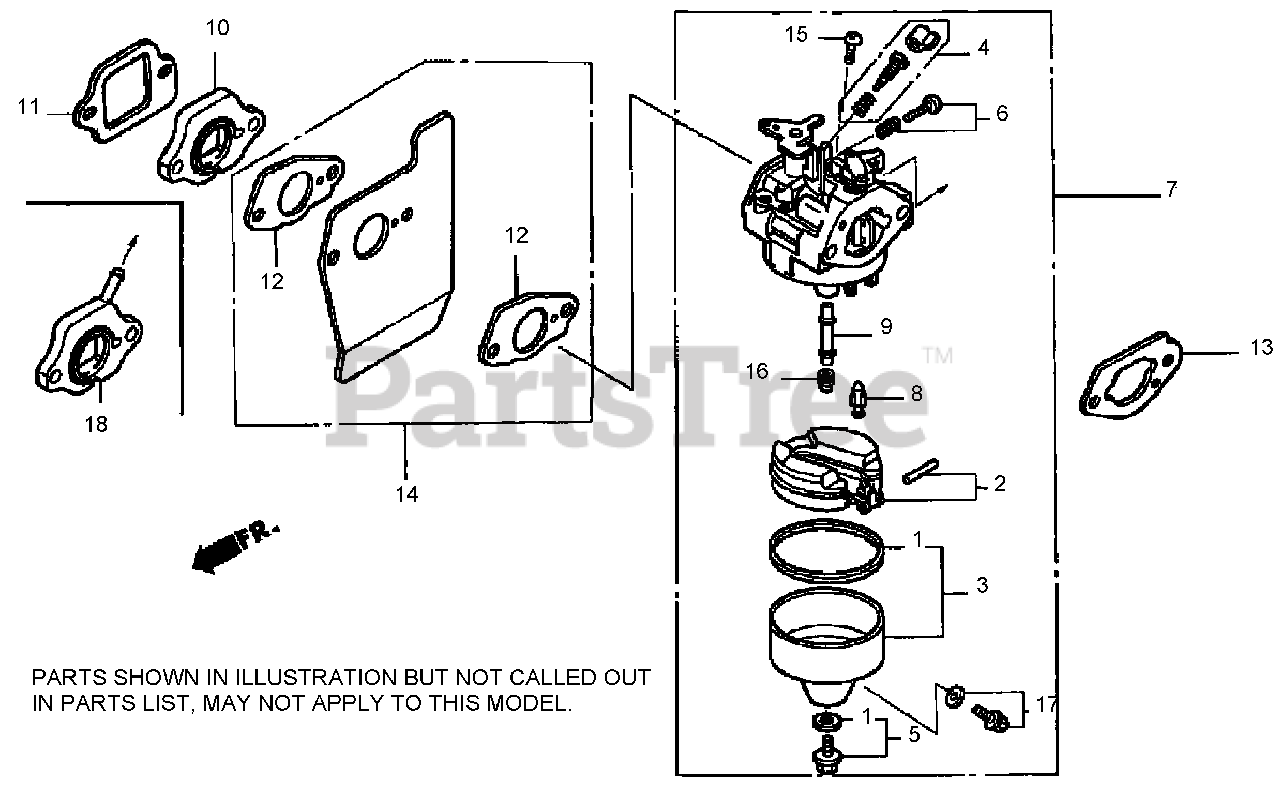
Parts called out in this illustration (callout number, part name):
1	GASKET SET
2	FLOAT SET
3	CHAMBER SET, FLOAT
5	SCREW SET B
7	CARBURETOR ASM. (BB62G A)
8	VALVE, FLOAT
9	NOZZLE, MAIN
10	INSULATOR, CARBURETOR
11	GASKET, INSULATOR
12	GASKET, CARBURETOR
13	GASKET, CARBURETOR (CHOKE SIDE)
14	GUIDE, AIR
15	SCREW, PAN (5X6)
16	JET, MAIN (#60)
17	SCREW SET, DRAIN
